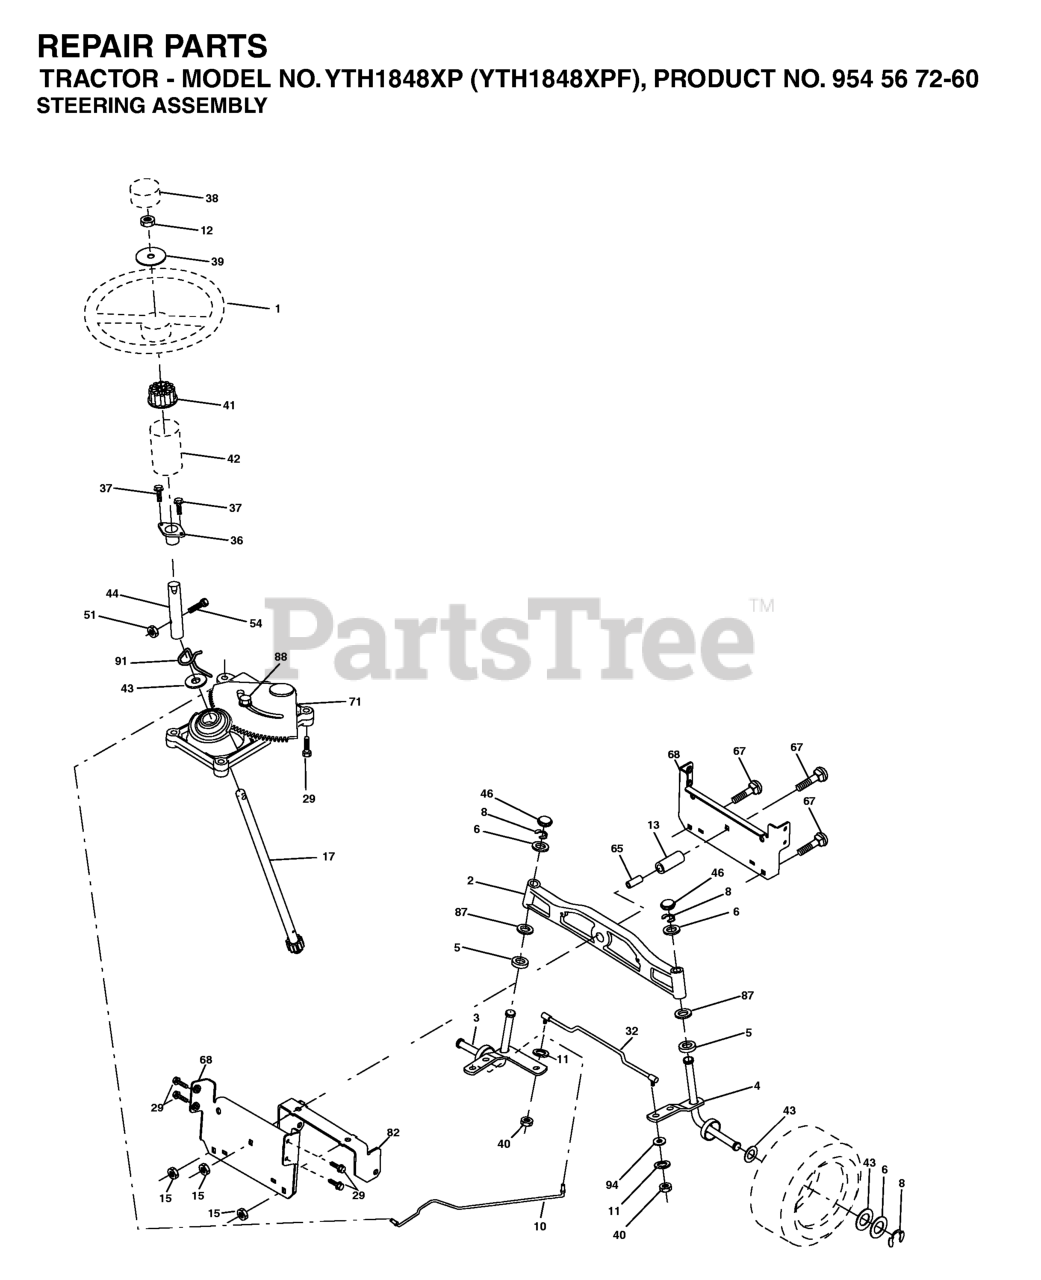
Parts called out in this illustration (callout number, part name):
1	STEERING WHEEL
2	AXLE ASM
3	SPINDLE.ASM.LH.15"TIRES
4	SPINDLE.ASM.RH.15"TIRES
5	THRUST WASHER
10	DRAGLINK.15".TIRES.2001
11	WASHER, LOCK 3/8
12	NUT.HEX.1/2-20
13	TUBE, PIVOT AXLE
15	NUT
17	SHAFT ASM, STEERING
29	SCREW 3/8-16X3/4
32	ROD TIE BALL J WSL
36	BUSHING, STEERING
37	SCREW.TT.#10-32X.5.3/8.FLANGE
38	CAP.WHEEL.STEERING.GREY
39	Washer 9/16 ID x 1 1/2 OD 11 Ga. Zin
40	GRIPCO NUT
41	STEERING WHEEL ADAPTOR
42	BOOT STEERING
44	EXT, STEERING SHAFT
46	CAP.SPINDLE.BLACK
51	NUT.CROWNLOCK.1/4-28
54	Bolt Hex 1/4-28 unf x 1-1/4 Gr. 8
65	SPACER BRACE AXLE
67	BOLT
68	BRACE.AXLE.15"TIRES
71	STEERING ASM
82	BRACKET
87	WASHER, FLAT .781 X 1 1/2"
88	BOLT, SHOULDER 7/16-20
91	CLIP.STEERING
94	WASHER.5/16.FLAT.STE.STD.
